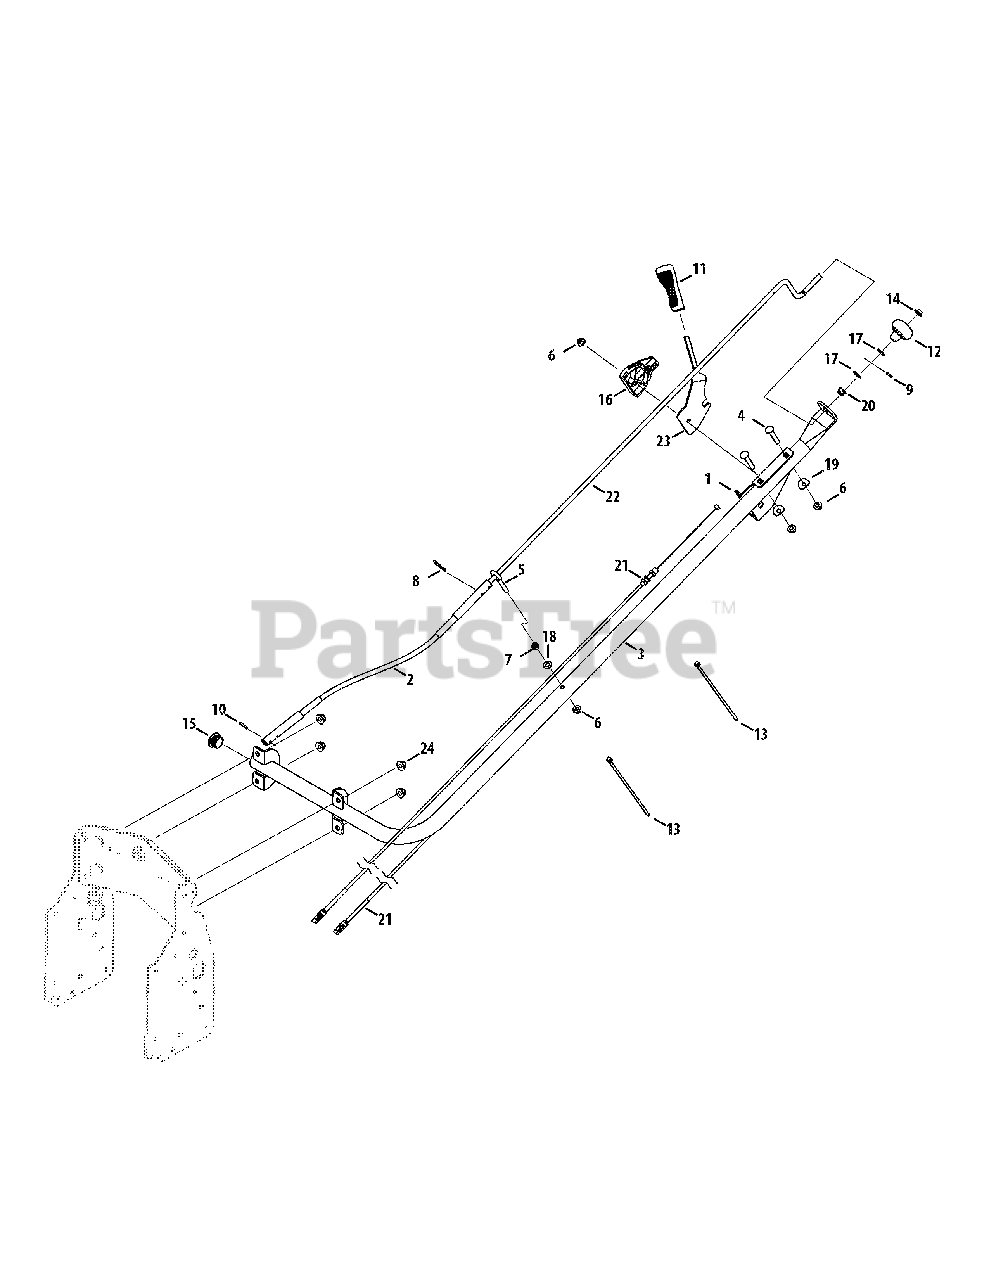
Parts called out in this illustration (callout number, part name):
1	Assembly, Chute Tilt Bracket
2	Control Assembly
3	Bracket Assembly
4	Screw, Carriage, 5/16-18, 2.00, Gr5
5	Bolt, Eye, 5/16-18 x 3.25
6	Nut, Flange Lock, 5/16-18, Grf, Nylon
7	Nut, Hex, 5/16-18, Gr5
8	Pin, Cotter, Int .08 x 1.42
9	Pin, Roll, 1/8 OD, .63
10	Pin, Spg, .156 Dia x .875 Lg
11	Grip, Handle, 3/8
12	Knob, .390 ID
13	Cable, Tie, 3/16 x .05 x 7.4
14	Cap, Push, 3/8 Rod
15	Plug, But, 1.250 Thin Wall
16	Guide, Cable, Chute Tilt
17	Washer, Flat, .375 x .738 x .063
18	Washer, Flat, .344 x .688 x .065
19	Washer, Saddle, .320 x .930 x .060
20	Bearing, Flange, Snap .385 ID
21	Cable, 74.5 Lg
22	Crank, Chute, .375 Dia x 34.63
23	Handle, Bracket, Chute Tilt
24	Nut, Flange Lock, 3/8-16, Grf, Nylon
